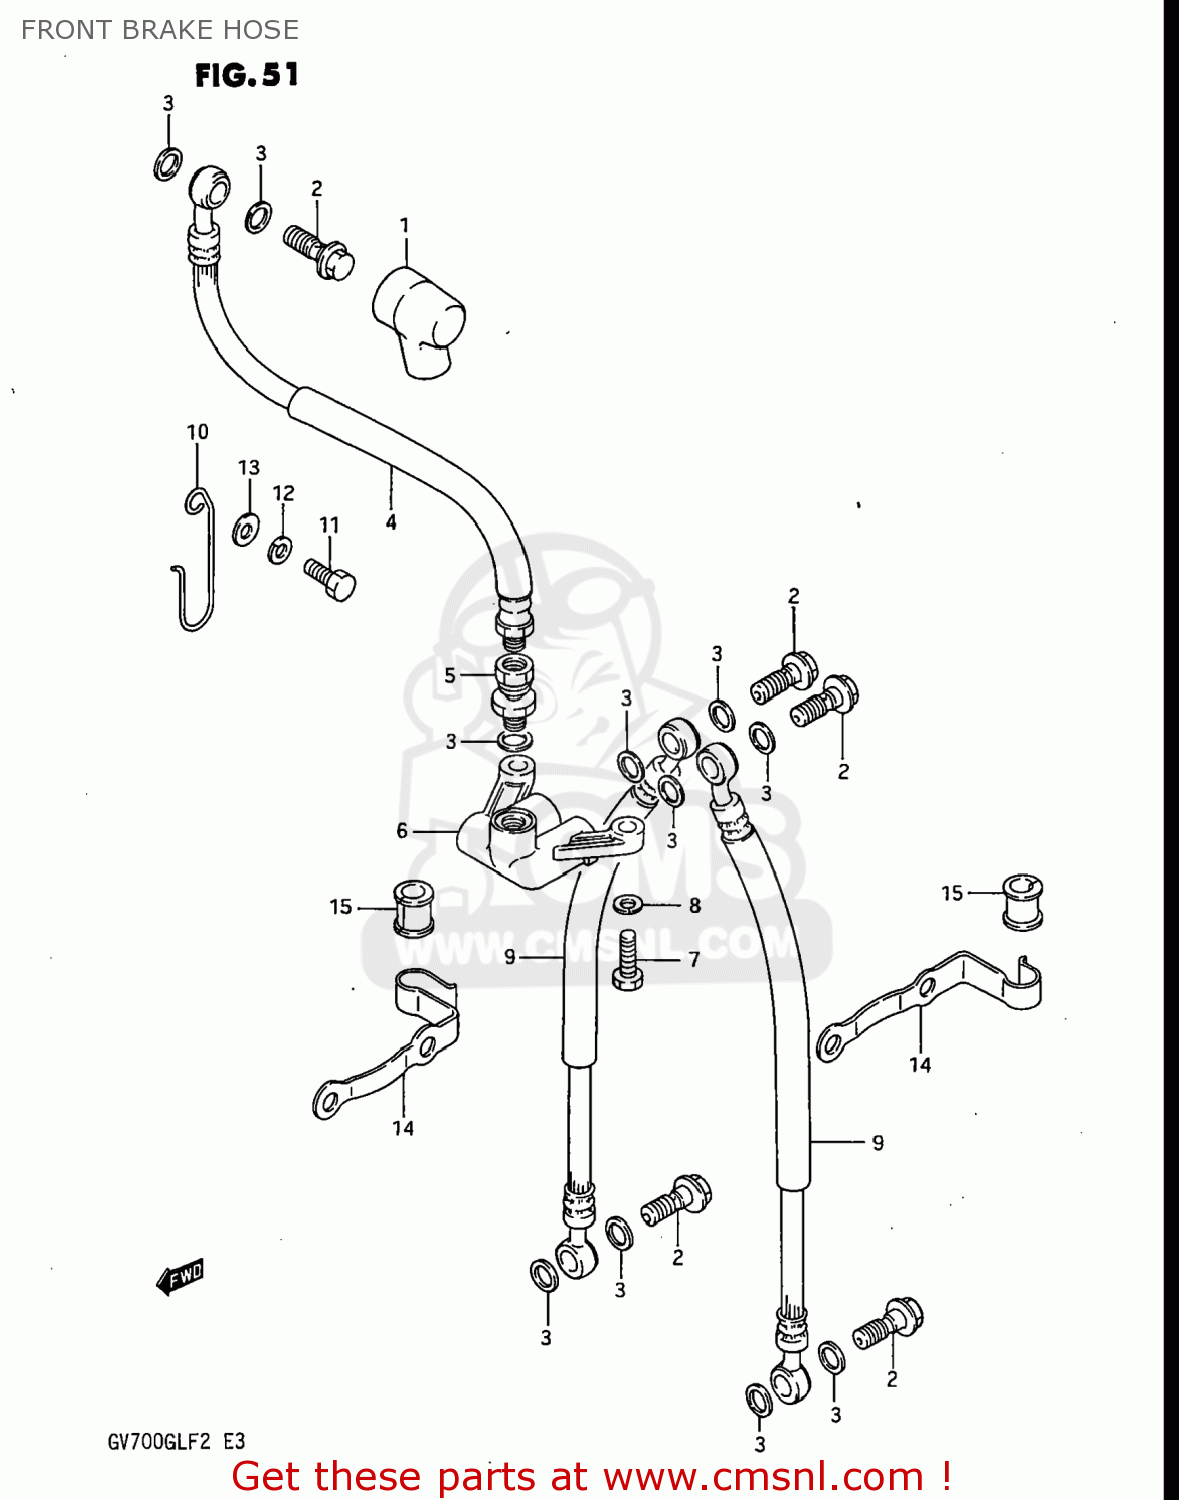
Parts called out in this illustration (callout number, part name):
1	BOOT,MASTER CYLINDER
2	BOLT UNION
3	WASHER(10X15X1.5)
4	HOSE,FRONT BRAKE NO.1
5	ADAPTER,BRAKE HOSE
6	JOINT,BRAKE HOSE
7	BOLT
8	LOCK WASHER
9	HOSE,FRONT BRAKE NO.2
10	GUIDE,CLUTCH HOSE
11	BOLT
12	LOCK WASHER
13	WASHER
14	GUIDE,BRAKE HOSE NO.2
15	BUSH,BRAKE HOSE GUIDE,NO.2
